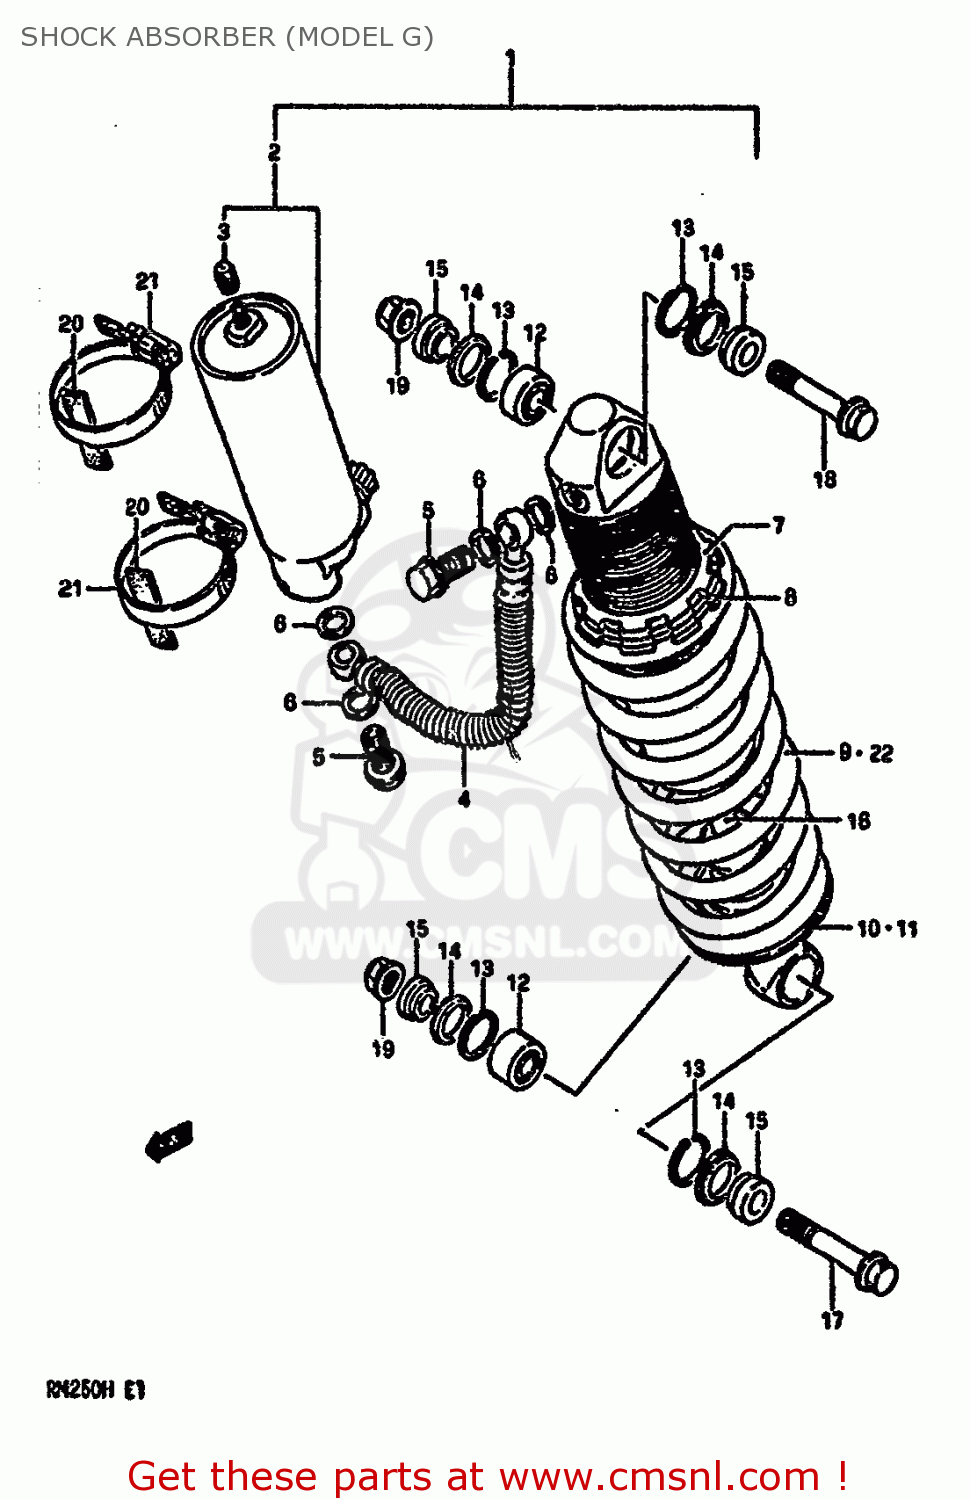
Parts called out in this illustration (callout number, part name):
1	ABSORBER ASSEMBLY,REAR SHOCK
2	TANK
3	CAP
4	HOSE
5	BOLT,REAR SHOCK ABSORBER
6	GASKET (NAS)
7	NUT
8	GUIDE,SPRING
9	SPRING
10	WASHER
11	GUIDE,SPRING
12	BEARING,REAR SHOCK ABSORBER
13	RING
14	SEAL,DUST RR SHOCK ABSORBER
15	COLLAR
16	ROD,PISTON
17	BOLT,REAR SHOCK ABSORBER
18	BOLT,UPPER
19	NUT
20	CUSHION,REAR SHOCK ABSORBER
21	CLAMP
22	SPRING,REAR (SOFT)
